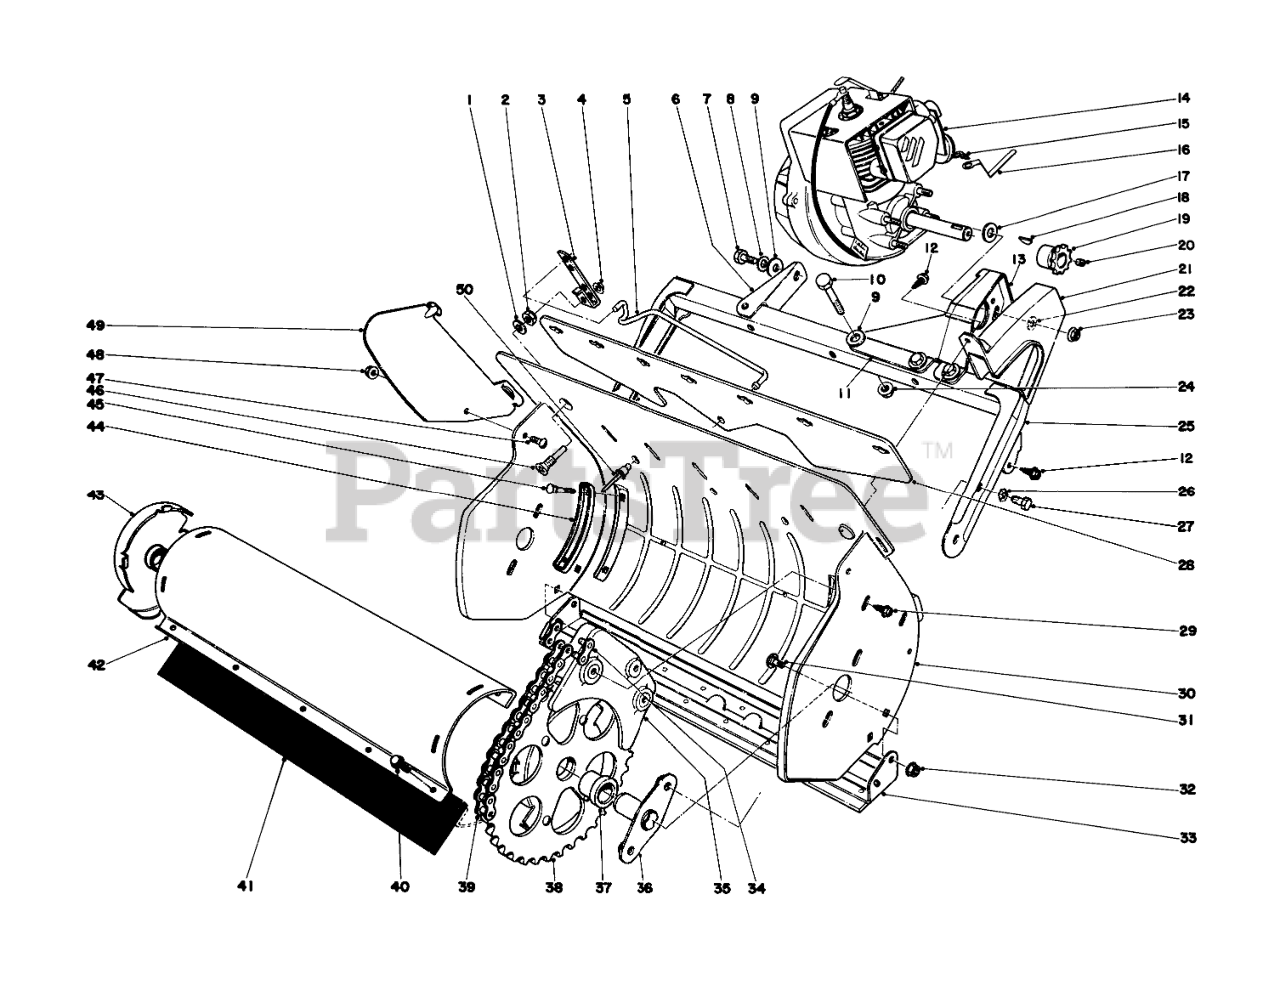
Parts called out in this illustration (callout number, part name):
1	WASHER-FLAT
2	NUT-LOCK, NI
3	Bracket-Vane Adj.
4	NUT-SPEED
5	Linkage Vane Adj.
6	Bracket
7	1/4-20 X 5/8 CAPSCREW
8	WASHER-LOCK/EXT
9	WASHER-FLAT
10	SCREW-HH
11	Bracket Engine
12	SCREW-HWHTF
13	Bracket Engine
14	Engine
15	Cotter Pin
16	Choke Strap
17	WASHER-PLAIN
19	SPROCKET
20	SCREW-SET, HSH
21	Chain Guard
22	Lockwasher
23	NUT-HHF
24	NUT-LOCK, HHF
25	Frame Assembly (Incl. Ref. #6, 9-11, 12&24)
26	Washer
27	Screw
28	Vane Mount
29	Screw
30	Housing
31	SCREW-CARR
32	NUT-KEPS
33	Skid
34	LINK-CONNECTING, NO. 35
35	Stripper
36	Rotor Shaft
37	ROTOR BUSHING
38	End Cap Assembly L.H.
39	CHAIN
40	SCREW-TAP
41	ROTOR BLADE
42	ROTOR SHELL
43	End Cap Assembly R.H.
44	Handle Plate
45	SCREW-CARR
46	Screw
47	SCREW-PTH
48	NUT-LOCK, FLANGE
49	Vane
50	RIVET
